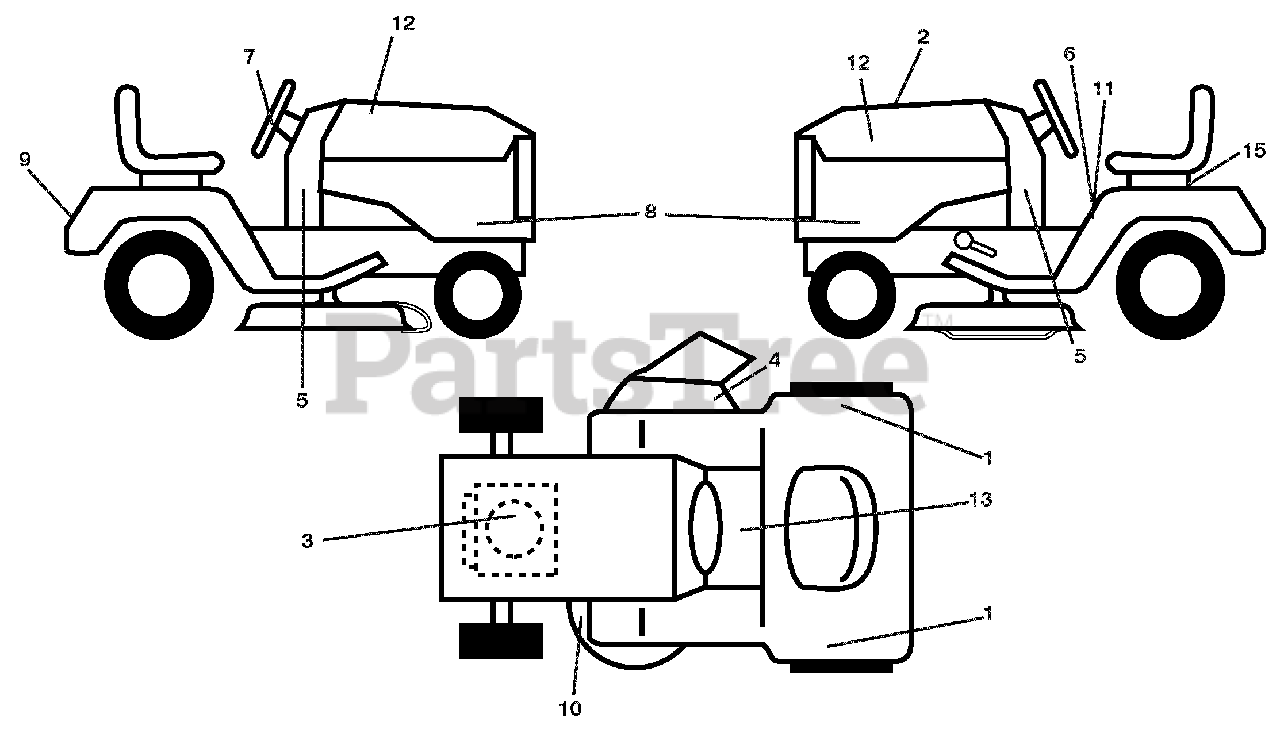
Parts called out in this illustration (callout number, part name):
1	DECAL.FENDER.SIDE.HYDRO
2	DECAL.REPLACEMENT
3	DECAL.ENGINE.HP
4	DECAL DECK/DEFLECT. WARNING
5	DECAL, DASH.LOWER
6	DECAL.WARNING.START
7	DECAL.WHEEL.STEER.ARIENS
8	DECAL.SDPNL.PWRDBY B&S.ARIENS
9	DECAL.FENDER.REAR.ARIENS
10	DECAL.V-BELT.SCH.
11	DECAL.FENDER
12	DECAL.HOOD.LH/RH.
13	Decal, Spark Arrester
15	DECAL.BAT.DAN/POI P/L SYM.WPN
